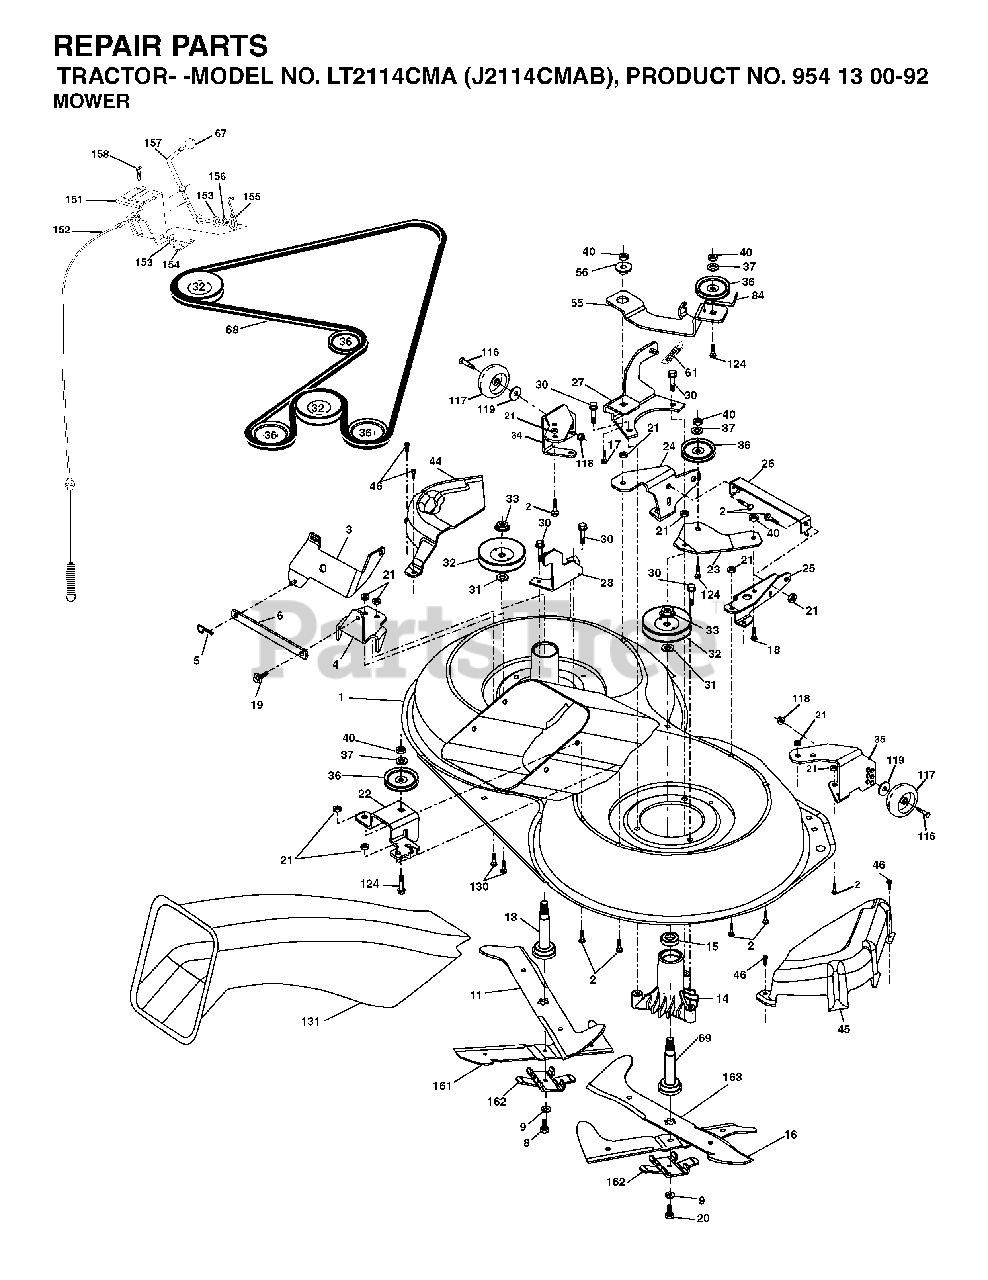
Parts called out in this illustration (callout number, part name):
1	MOWER HOUSING, DECK
2	BOLT
3	BRACKET
5	RETAINER-SPRNG RB
6	BAR SWAY
9	LOCKWASHER
11	BLADE-LH 5PT STAR(CTH130)
13	SHAFT ASM VENT
14	HSG MANDREL
16	BLADE RH 6PT STAR(CTH130)
17	BOLT.3/8-14X1.25
19	BOLT SHD 5/16-18
21	LOCKNUT
24	BRACKET
25	BRACKET
26	BRACE
28	BRACKET
30	SCREW, WASHER HEAD
31	WASHER
32	PULLEY, MANDREL
33	NUT, FLG TOPLOCK 9/16"
36	PULLEY.IDLER.4.25
40	LOCKNUT
45	MANDREL COVER
46	SCREW.1/4-20X5/8
55	ARM IDLER
56	SPACER.RETAINER.MOWER
61	SPRING.TENSION.BELT
67	KNOB T (3/8 HOLE)
68	HEX-BELT
69	SHAFT.ASM.W/LWR.BRG.RH.THREAD
84	KEEPER, BELT IDLER
116	SHOULDER BOLT
117	WHEEL GAGE DONUT
118	LOCKNUT
119	WASHER
124	BOLT.3/8-16X1.50
131	CHUTE BAGGER
151	BRACKET, CLUTCH CABLE
153	WASHER FLAT 3/8"
154	SPRING RETAINER
155	SPRING RETENTION LEVER
156	SPACER CLUTCH CABLE
157	ROD CLUTCH CABLE 3/8"
158	SCREW
